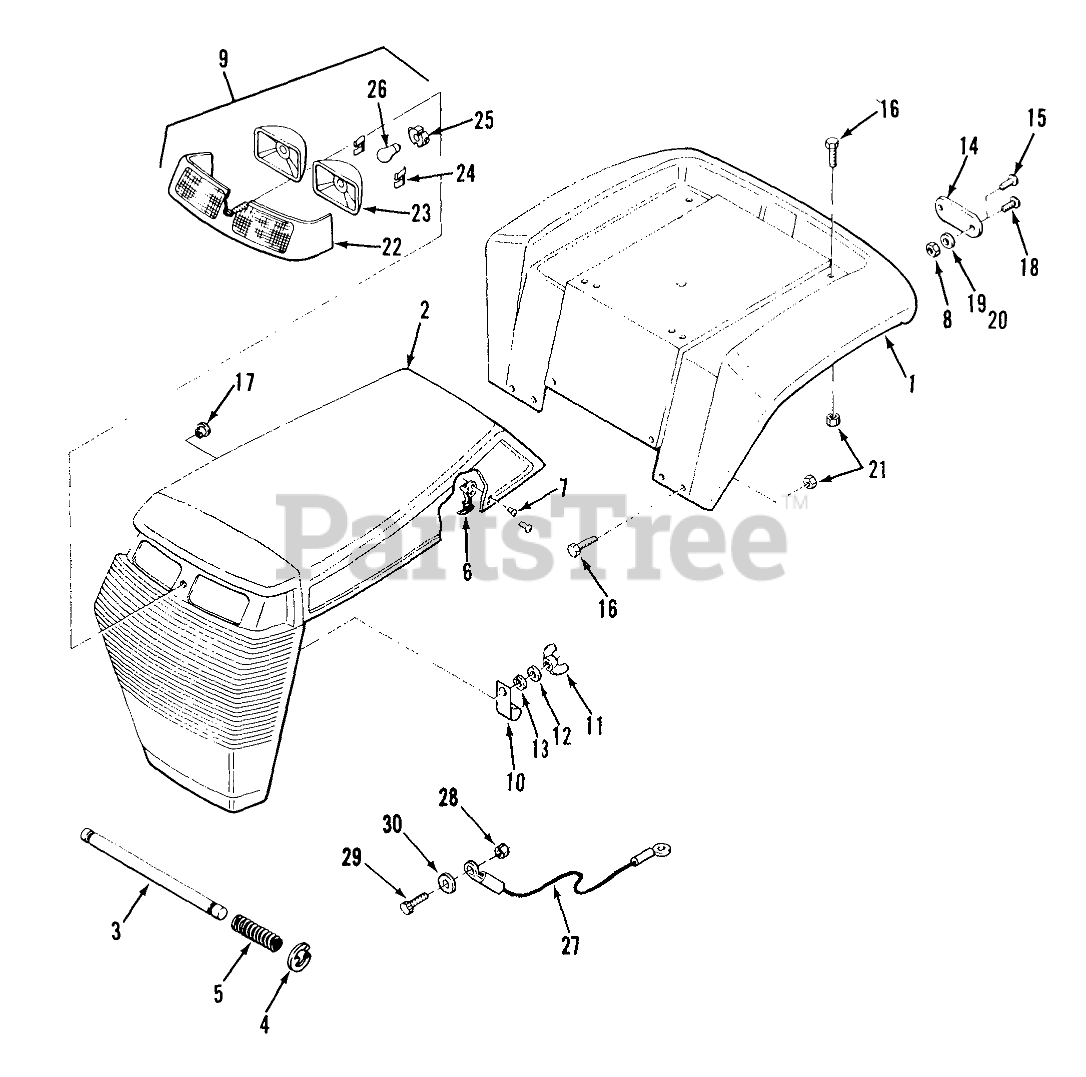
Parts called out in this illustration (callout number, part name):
1	FENDER R
2	Hood & Grill 211-4 & 211-5
4	E-Ring
5	SPRING
6	ASSY-FLEX DRAW LATCH
7	RIVET
8	Nut
9	Head Light Bar (includes items 22, 23, 24, 25, & (2) of 26)
10	J-CLIP
11	Nut-Wing
12	WASHER
13	LCKWSHR 1/4 INT TTH
14	Reflector
15	Poprivet
16	Bolt-Carriage
17	BUSHING-NYLON 1.093
18	Screw
19	WASHER
20	Lockwasher
21	Nut
22	Light Bar
23	LIGHT POD
24	RETAINER
25	SOCKET-LIGHT
26	BULB
27	CABLE-HOOD LANYARD
28	Nut
29	Screw-Machine
30	WASHER-BACKING
